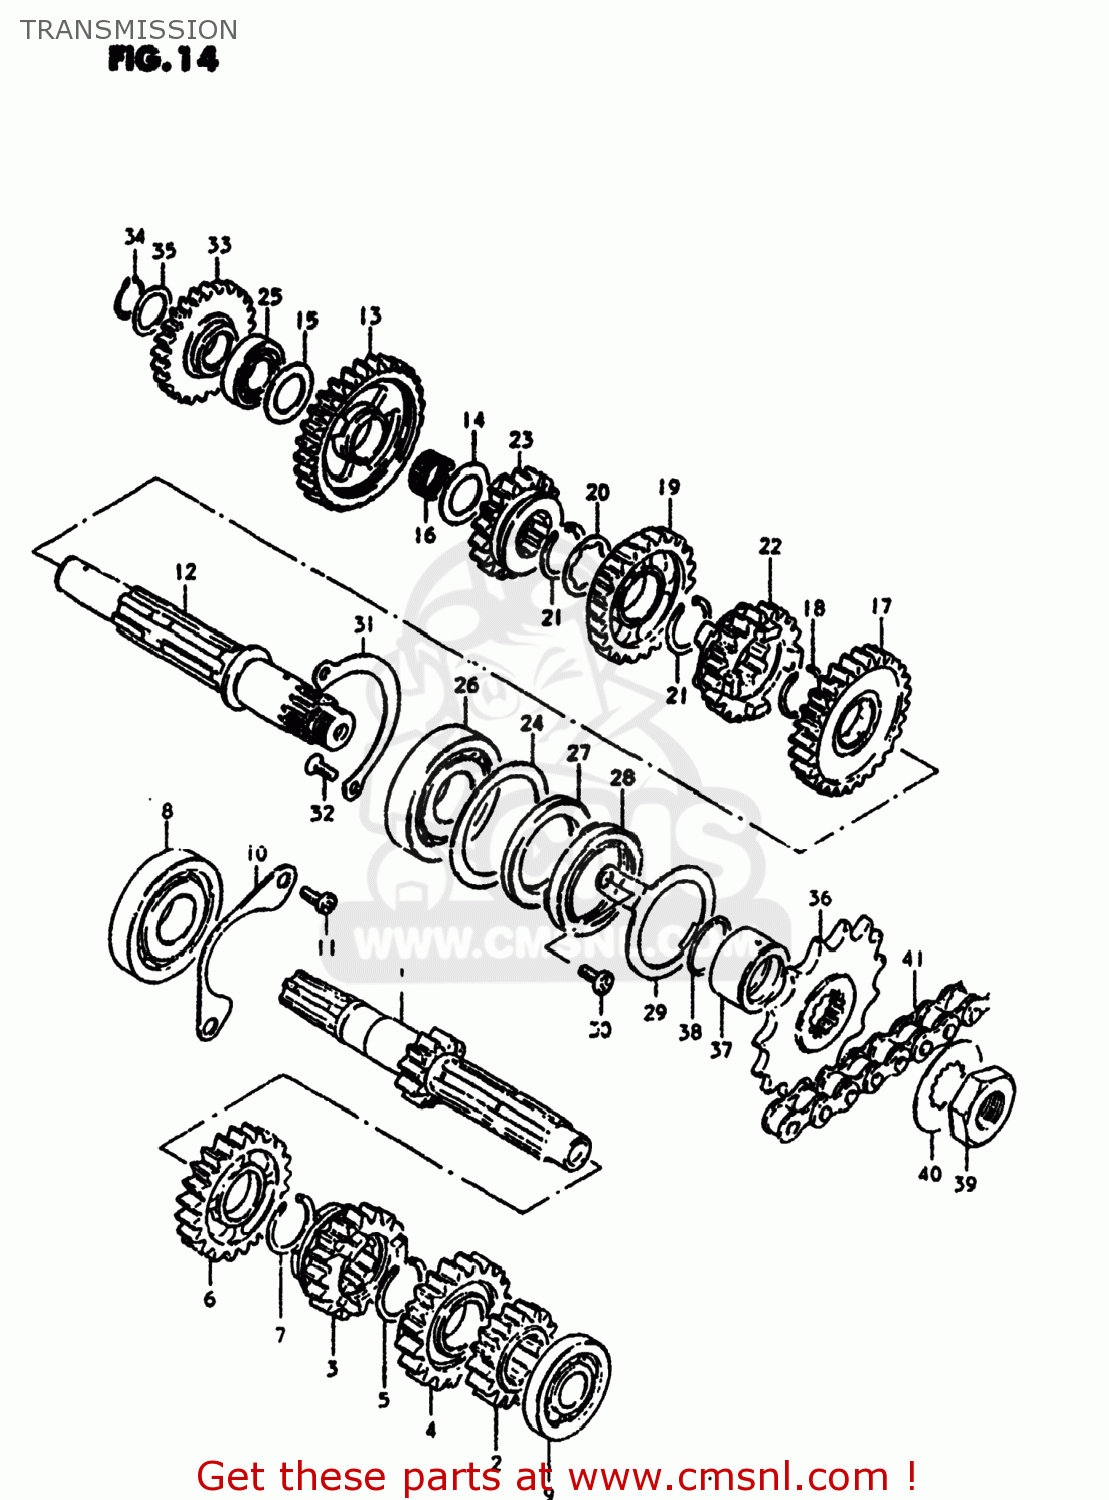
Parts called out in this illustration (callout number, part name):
1	SHAFT,COUNTER
2	GEAR,SECOND DRIVE
3	GEAR,THIRD DRIVE
4	GEAR,FOURTH DRIVE
5	CIRCLIP
6	GEAR,FIFTH DRIVE
7	CIRCLIP
8	BEARING
9	BEARING
10	PLATE,COUNTERSHAFT BEARING
11	SCREW 6X12
12	SHAFT,DRIVE
13	GEAR,FIRST DRIVEN
14	WASHER
15	WASHER
16	BEARING(17X21X9.8)
17	GEAR,SECOND DRIVEN
18	CIRCLIP
19	GEAR,THIRD DRIVEN
20	WASHER,LOCK
21	CIRCLIP
22	GEAR,FOURTH DRIVEN
23	GEAR,FIFTH DRIVEN
24	WASHER
25	BEARING(17X36X12)
26	BEARING(22X56X16)
27	OIL SEAL (30X47X5)
28	SEAL,OIL(30X47X7)
29	PLATE,DRIVESHAFT OIL
30	SCREW 6X12
31	RETAINER,DRIVE SHAFT BEARING
32	SCREW
33	GEAR,KICK STARTER IDLER(NT:25)
34	CIRCLIP
35	WASHER
36	SPROCKET,ENGINE(NT:15)
37	SPACER,ENGINE SPROCKET
38	O RING(D:2.5,ID:21)
39	NUT
40	WASHER,LOCK
41	CHAIN ASSEMBLY,DRIVE
